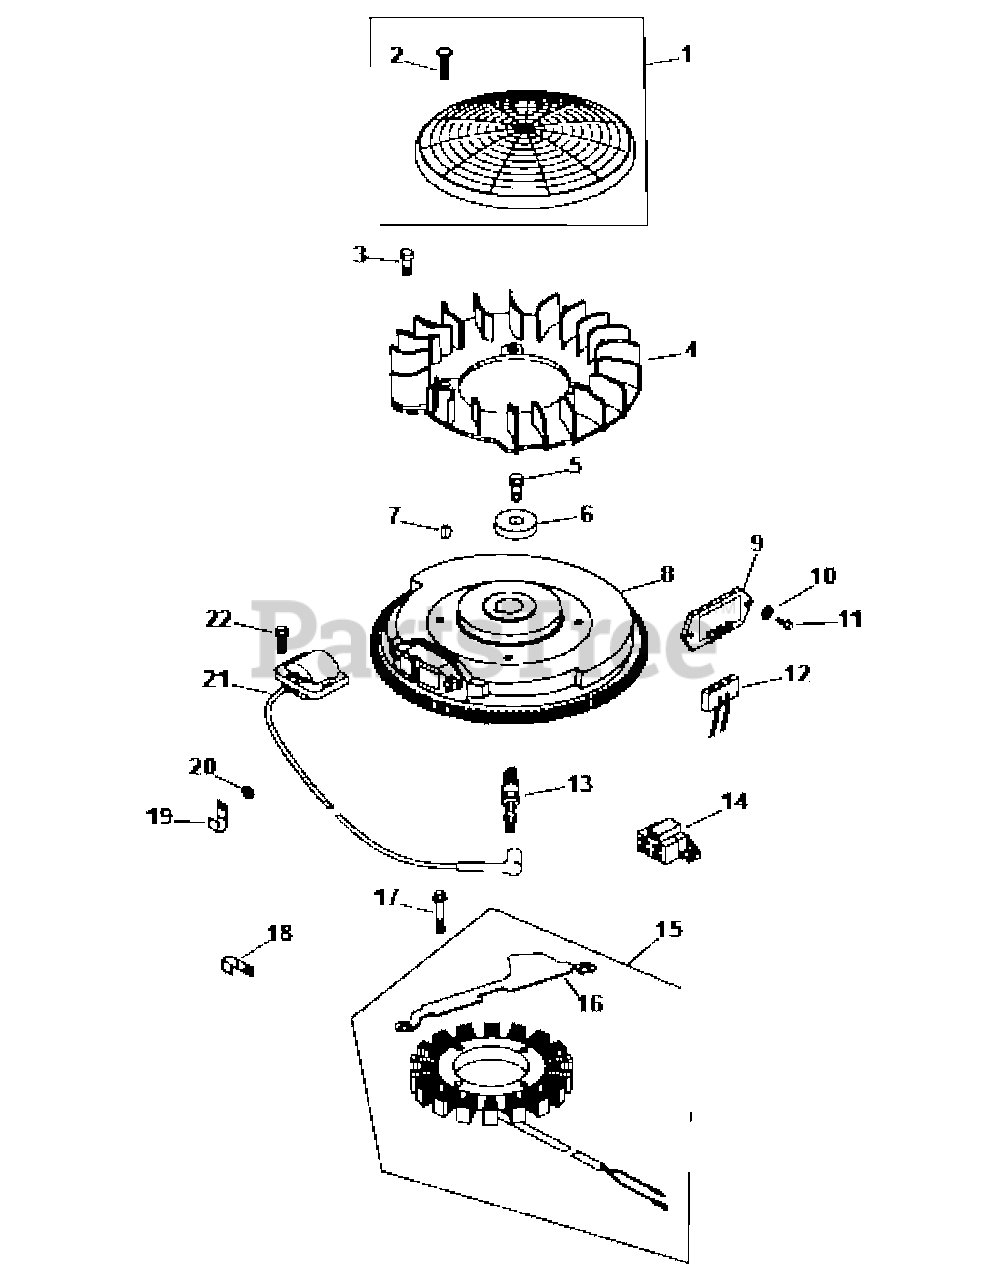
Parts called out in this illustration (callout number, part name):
1	Grass Screen Kit
3	Shoulder Bolt
4	Fan
5	Hex Flange Screw
8	Flywheel
9	Regulator Rectifier
11	Hex Head Screw
12	Connector
13	Spark Plug
15	15 amp Stator
16	Stator Wire Bracket
17	Hex Head Screw
18	Cable Clip
21	Ignition Module
22	Screw
